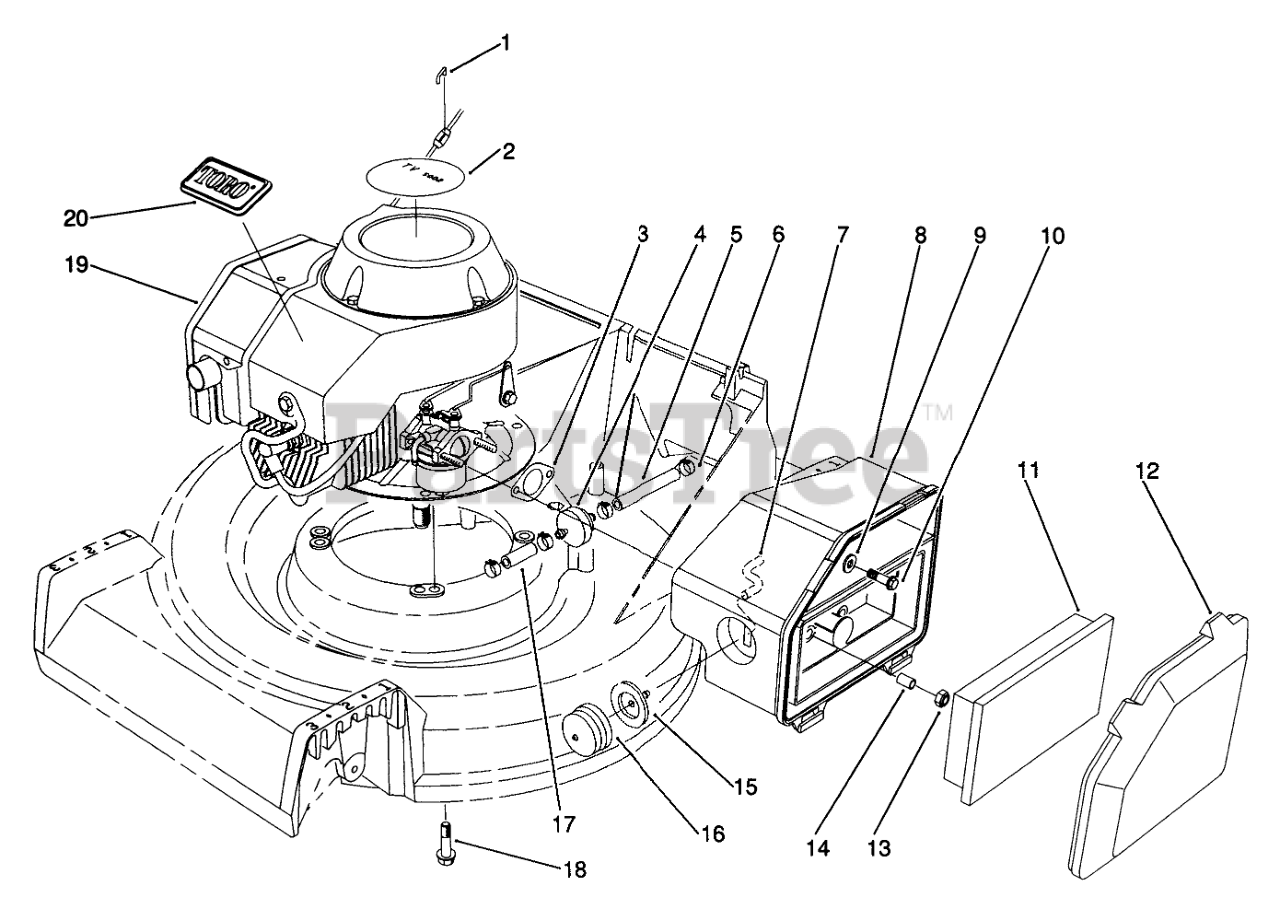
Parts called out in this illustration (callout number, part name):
1	Staple
2	DECAL-2 CYC RECOIL COMM
3	GASKET-AIR CLEANER
4	FILTER-FUEL
5	HOSE-FUEL
6	CLAMP-FUEL LINE
7	HOSE-PRIMER
8	BODY-AIR CLEANER
9	WASHER-FLAT
10	SCREW-HH
11	ELEMENT-AIR CLEANER
12	COVER-AIR CLEANER
14	SPACER
15	BODY-PRIMER
16	BULB-PRIMER
17	LINE-GAS
18	Bolt-Engine
19	ENGINE ASM
20	TORO LOGO PLT
